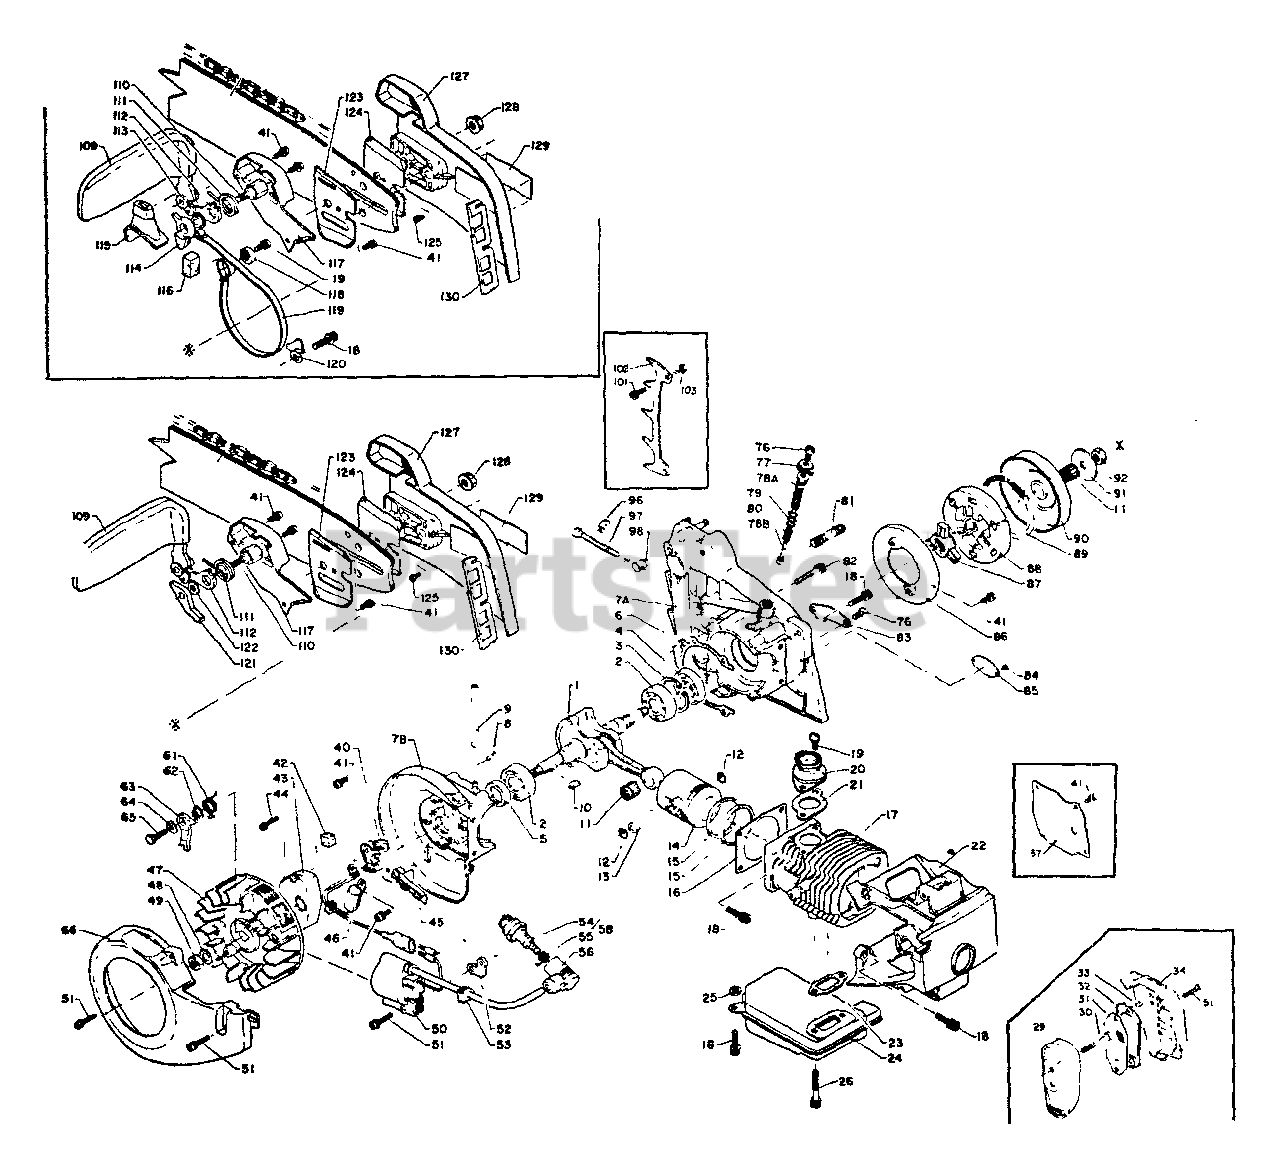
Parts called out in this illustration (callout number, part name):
1	CRANKSHAFT ASSY
2	BEARING, BALL 6202
3	RING, SNAP 35
4	SEAL, OIL 18
5	SEAL, OIL
6	GASKET, CRANKCASE
7	CRANKCASE KIT
7A	CRANKCASE KIT
7B	CRANKCASE KIT
8	PIN, LOCATING 4
9	PIPE, IMPULSE 3×6×75
11	BEARING, NEEDLE
12	RING, SNAP 8
13	PIN, PISTON
14	PISTON
15	RING, PISTON
16	GASKET, CYLINDER
17	CYLINDER
18	BOLT 5×20
19	SCREW 5×10
20	ADAPTER, INTAKE
21	GASKET, INTAKE
22	COVER, ENGINE
23	GASKET, EXHAUST
24	MUFFLER
26	BOLT M5×35
29	ADAPTER
30	SCREW 5×35
31	SCREEN, SPARK ARRESTER
32	RETAINER, SCREEN
33	SCREW 5×8
34	COVER, EXHAUST
37	COVER, CYLINDER
40	CONTACT POINT SET
41	SCREW 4×10
42	PAD, OIL
43	COVER, BREAKER
44	SCREW 3×18
45	CLAMP
46	CONDENSER
47	FLYWHEEL
50	COIL, IGNITION
51	SCREW 4×20
52	SPACER
53	BUSHING
54	SPARK PLUG - BPM6A
55	TERMINAL, SPARK PLUG CAP
56	CAP, SPARK PLUG
58	SPARK PLUG - BPMR6A
62	SPACER
63	RATCHET
65	BOLT 5×18
66	SHIELD, FAN
75	SCREW, ADJUSTER
76	SCREW 5×10
77	LOCKWASHER
78	PUMP KIT
78A	PUMP KIT
78B	PUMP KIT
81	STUD, GUIDE BAR
82	BOLT 5×30
83	CATCHER, CHAIN
84	RIVET
85	MODEL PLATE
86	SEAL, DUST
87	HUB, CLUTCH
88	SHOE, CLUTCH
89	SPRING, CLUTCH
90	DRUM, CLUTCH - 3/8"
91	WASHER, CLUTCH
92	LOCKNUT
97	SCREW, TENSIONER
98	TENSIONER, CHAIN
101	BOLT 5×12
102	BUMPER, SPIKED
103	NUT M5
109	HAND GUARD (BRAKE HANDLE)
111	SPRING, RETURN
113	SPACER
114	CONNECTOR
115	COVER, BRAKE
116	SEAL
117	COVER, BRAKE
118	ADJUSTER, BRAKE BAND
119	BAND, BRAKE
120	RETAINER
121	STOPPER
122	WASHER 6.5×11.5×0.8
123	PLATE, GUIDE - INNER
124	PLATE, GUIDE - OUTER
125	SCREW 3×6
127	GUARD, SPROCKET
128	NUT, FLANGE M8×1.25
129	LABEL - ECHO
130	PROTECTOR
